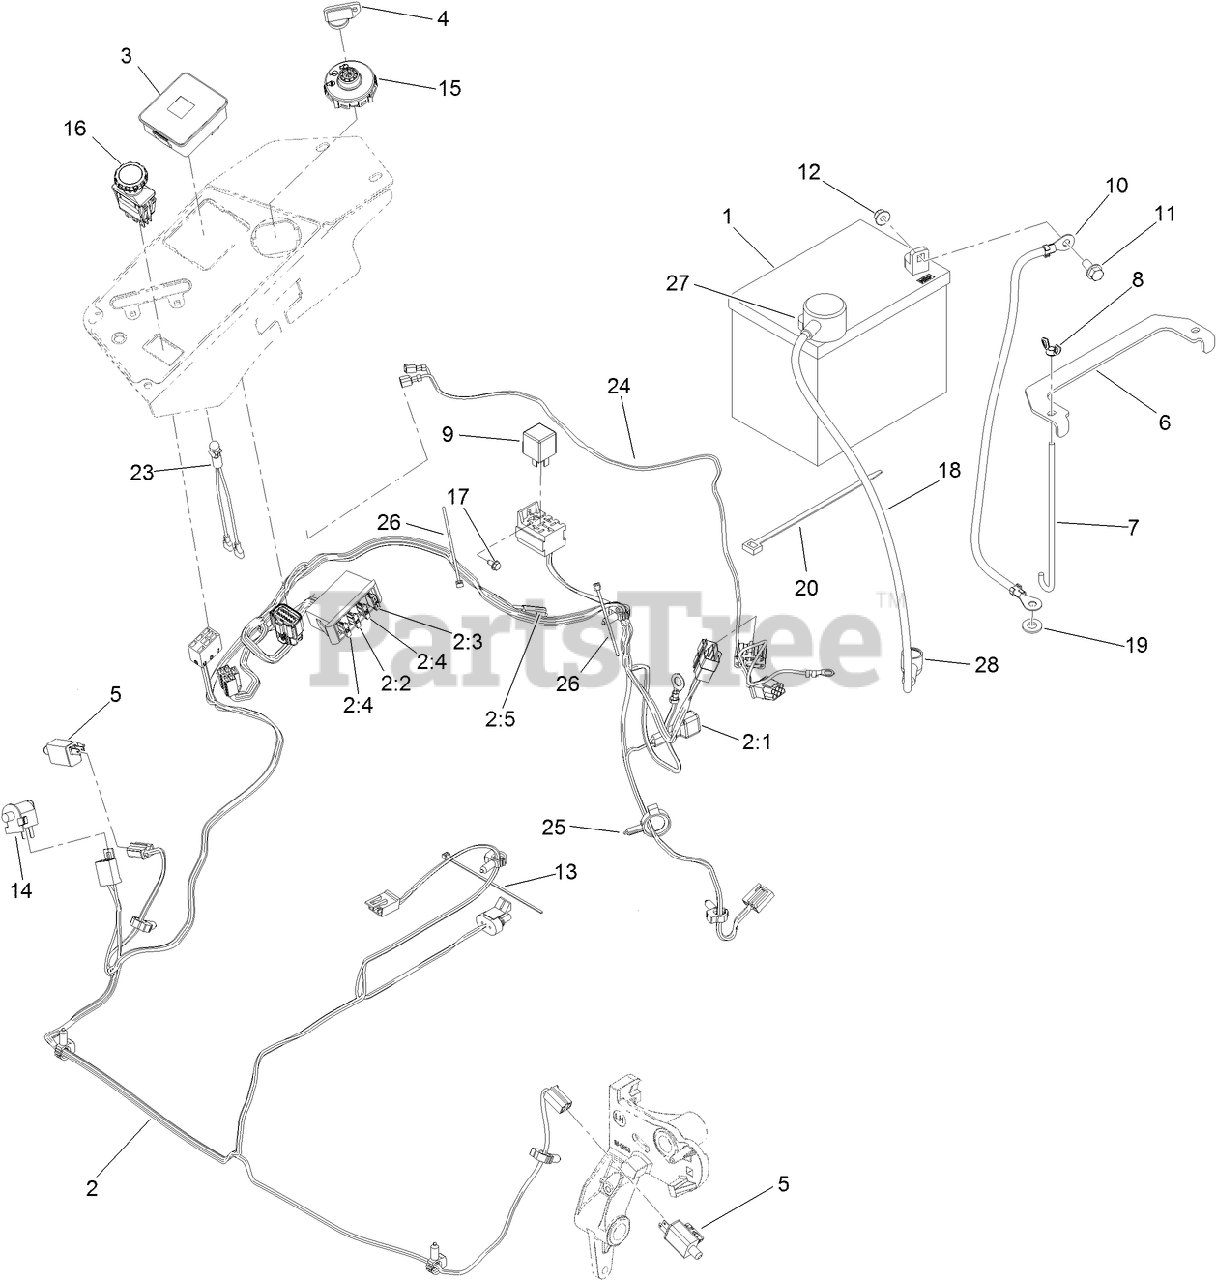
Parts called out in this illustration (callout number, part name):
1	BATTERY-DRY
2	HARNESS-WIRE, MAIN
2:2	FUSE-BLADE, 10 AMP
2:3	FUSE-BLADE, 15 AMP
2:4	FUSE-BLADE, 25 AMP
2:5	CAP-PLUG
3	FUEL/HOUR METER ASM
4	KEY-IGNITION
5	SWITCH
6	STRAP-TIE DOWN, BATTERY
7	BOLT-HOLDDOWN
8	WINGNUT
10	CABLE-BATTERY, NEGATIVE
11	SCREW-HHF
12	NUT-HF, NI
13	TIE-CABLE
14	SWITCH-BAIL
15	SWITCH-IGNITION
16	SWITCH-PTO, 10 AMP
17	SCREW-HWH
18	CABLE-BATTERY, POSITIVE
19	WASHER-FLAT
20	TIE-PLASTIC
23	INDICATOR-LED, RED
24	HARNESS-LIGHT, INDICATOR
25	CLAMP-HOSE
26	TIE-CABLE
27	INSULATOR-BATTERY
28	INSULATOR-SOLENOID
